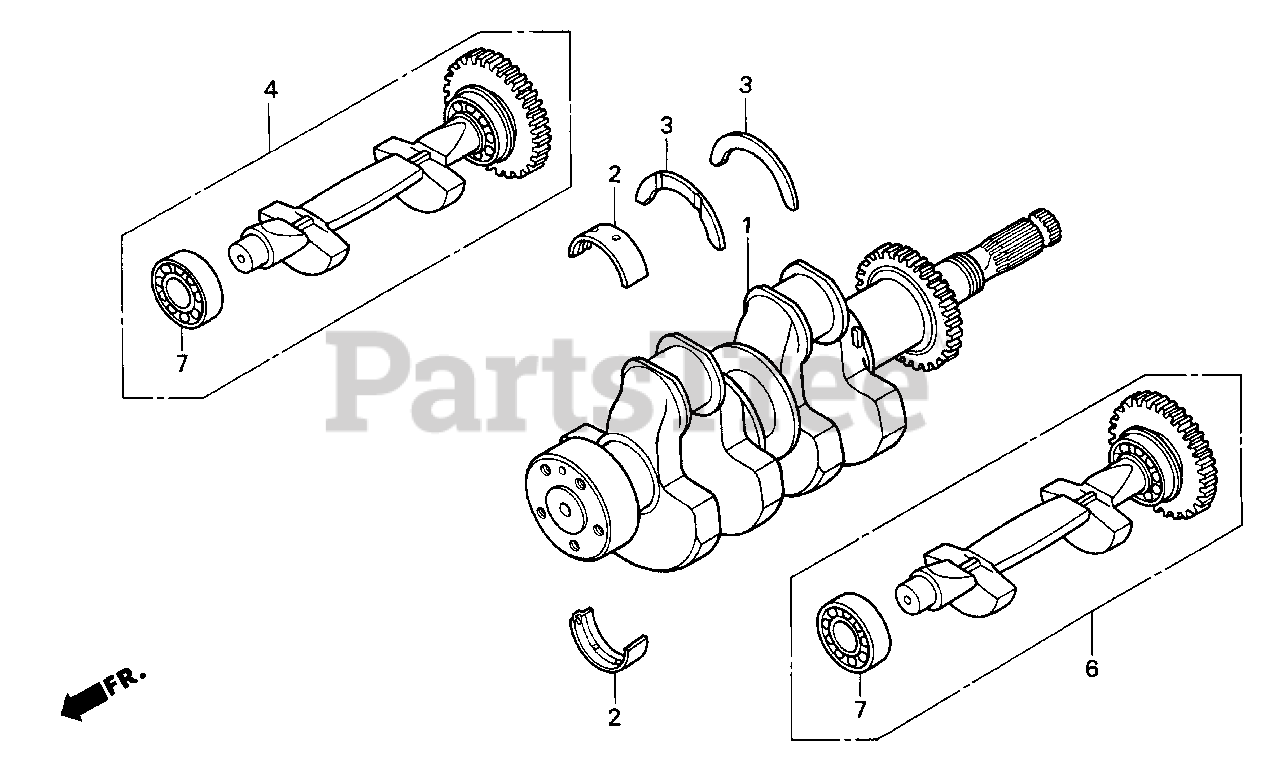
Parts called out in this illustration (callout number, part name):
1	CRANKSHAFT
2	BEARING A, MAIN (BLUE)
2	BEARING B, MAIN (BLACK)
2	BEARING C, MAIN (BROWN)
2	BEARING D, MAIN (GREEN)
2	BEARING E, MAIN (YELLOW)
2	BEARING F, MAIN (PINK)
2	BEARING G, MAIN (RED)
3	WASHER, THRUST
4	WEIGHT, R. BALANCER
6	WEIGHT, L. BALANCER
7	BEARING, RADIAL BALL (6203)
